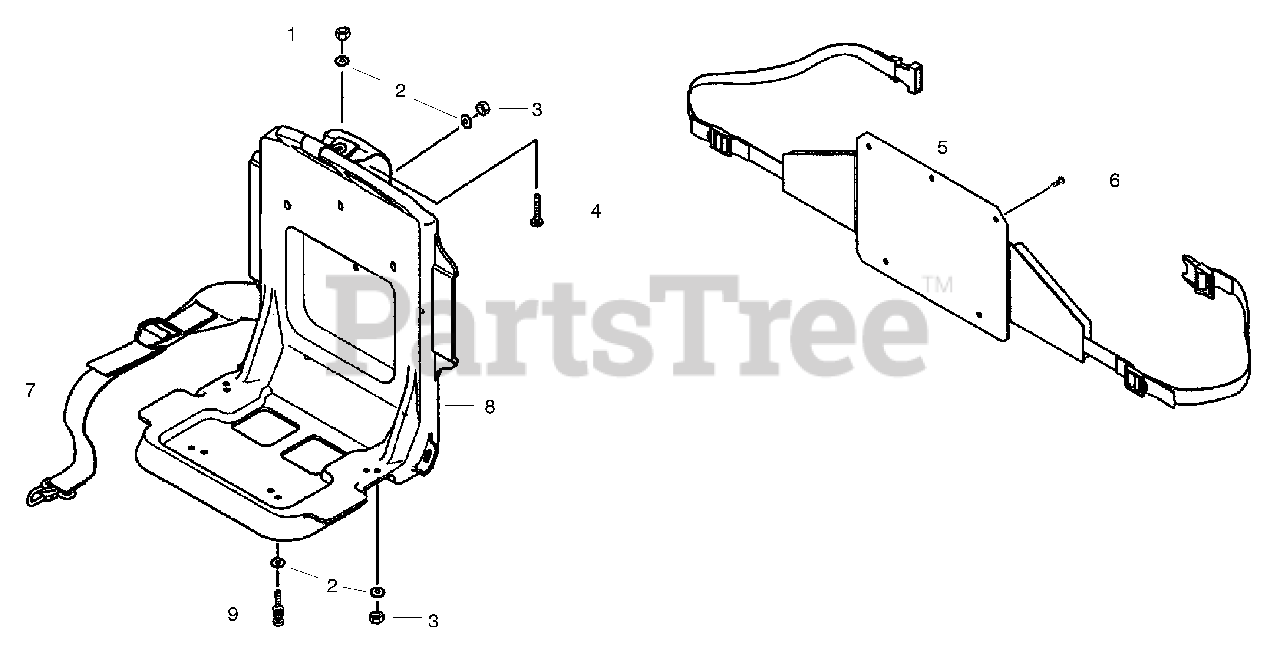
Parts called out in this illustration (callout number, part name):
1	Nut-Nylon Flange
3	Nut-Hex-U
4	Screw-Truss
5	Pad-Knapsack
7	Band-Shoulder
8	Frame-Knapsack
9	Screw m6x15
